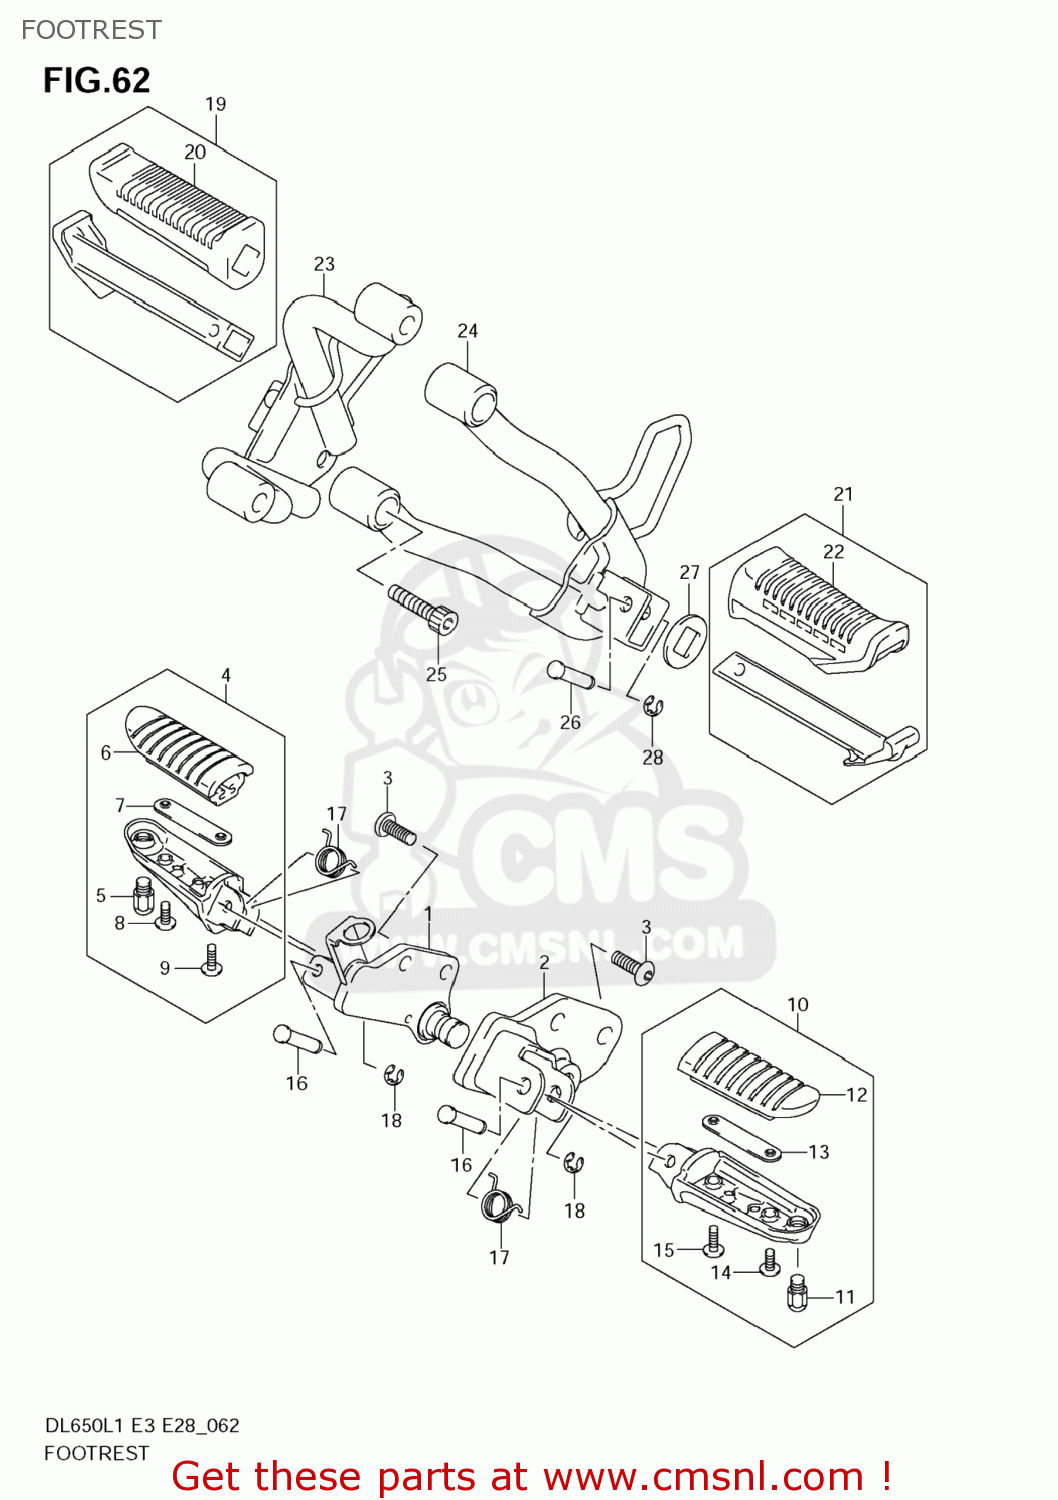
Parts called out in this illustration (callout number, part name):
1	BRACKET,FR FOO
2	BRACKET,FR FOO
3	BOLT(8X23)
4	FOOTREST ASSY,PILLION,R
5	BOLT,BANK SENSOR
6	RUBBER,FOOTREST
7	PLATE,FR FOOTREST RUBBER
8	SCREW
9	SCREW
10	FOOTREST ASSY,PILLION,L
11	BOLT,BANK SENSOR
12	RUBBER,FOOTREST
13	PLATE,FR FOOTREST RUBBER
14	SCREW
15	SCREW
16	PIN(8X33.2)
17	SPRING
18	E RING
19	FOOTREST ASSY,PILLION,R
20	RUBBER,FOOTREST
21	RUBBER,FOOTREST
22	FOOTREST ASSY,PILLION,L
23	BRACKET,PILLION FOOTREST,R
24	BRACKET,PILLION FOOTREST,L(BLA
25	BOLT(8X40)
26	PIN(6X29.5)
27	WASHER,FOOTREST RUBBER
28	E RING
